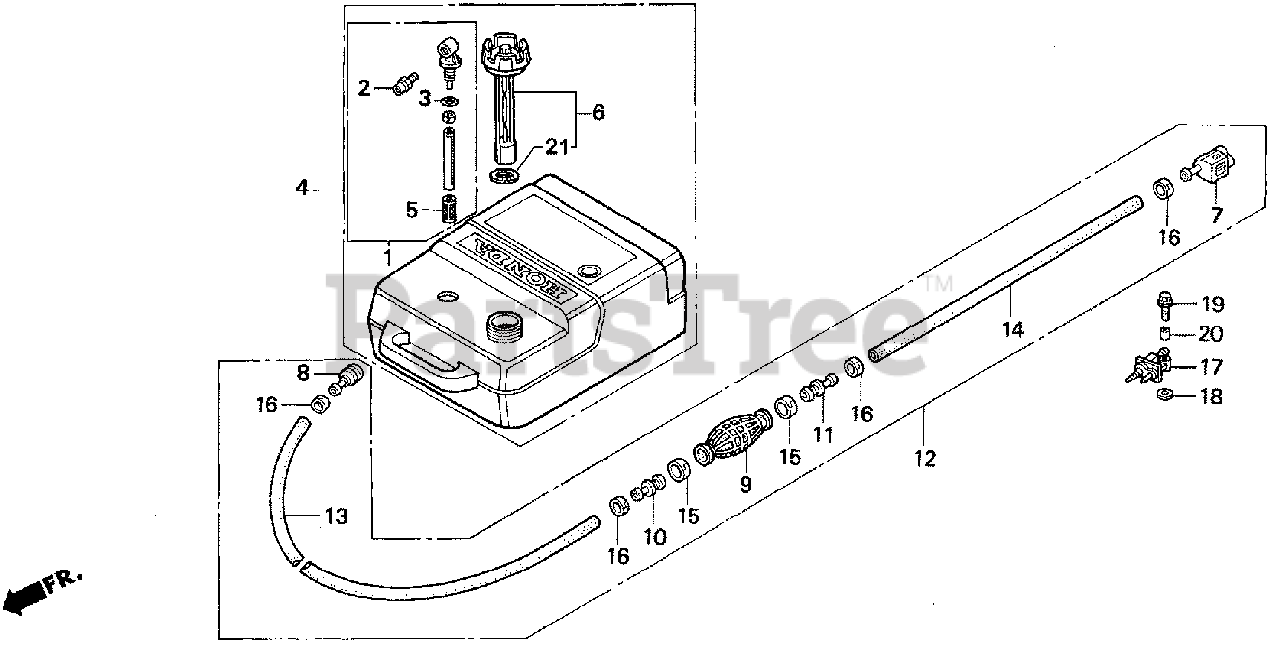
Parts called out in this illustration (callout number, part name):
1	FUEL JOIN, SET
1	JOINT ASSY., FUEL
2	FITTING, QUICK DISCONNECT
3	O-RING
4	TANK ASSY., FUEL
5	FILTER, FUEL
6	CAP, FUEL FILLER
7	CONNECTOR SET, FUEL
7	CONNECTOR ASSY. A, FUEL
8	CONNECTOR, FUEL
9	PRIMER BULB
10	VALVE, IN.
11	VALVE, OUTLET
12	TUBE ASSY., FUEL
13	TUBE, FUEL (7.5X2000)
14	TUBE, FUEL SHORT (6.3X500)
15	BAND, TUBE CLIP (20MM)
16	BAND, TUBE CLIP (12.5MM)
17	CONNECTOR SET, FUEL
17	CONNECTOR ASSY. B, FUEL
18	WASHER, PIVOT
19	BOLT, FLANGE (6X20)
20	COLLAR, DISTANCE (6MM)
21	GASKET, FUEL CAP
